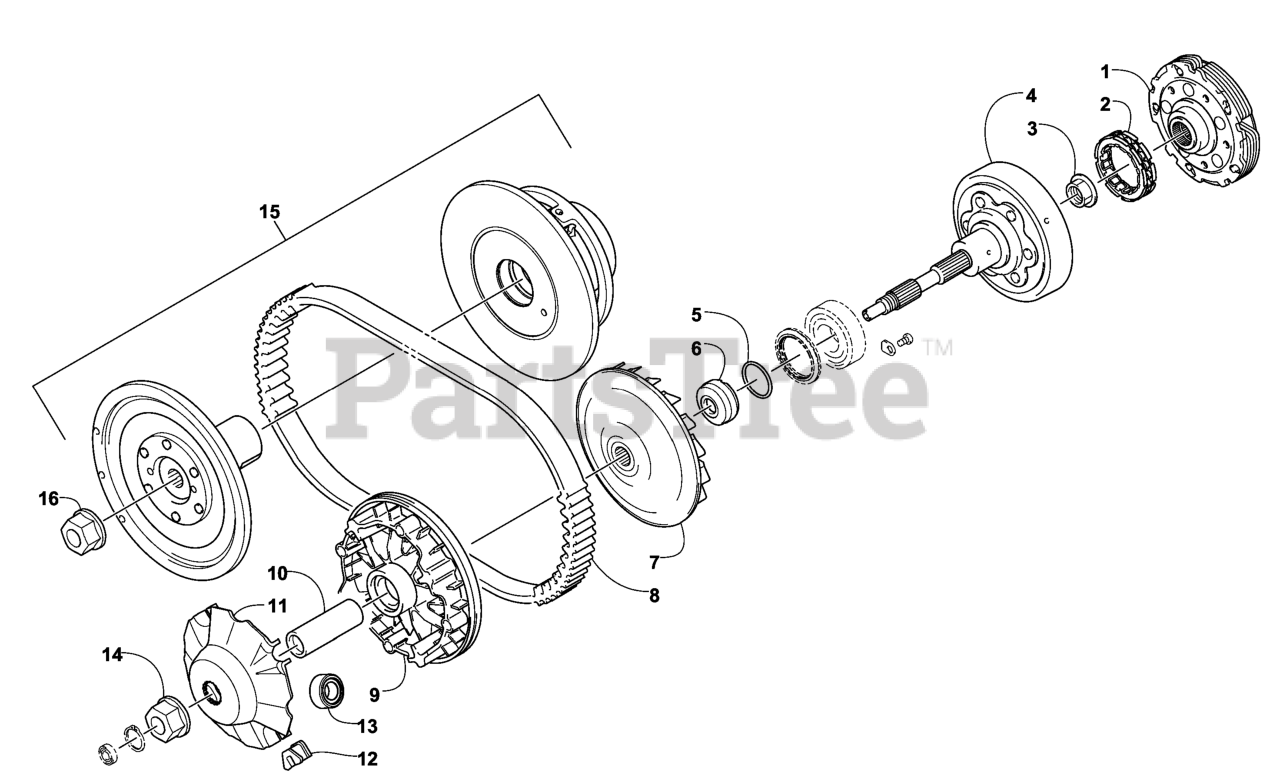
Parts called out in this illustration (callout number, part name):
1	PRIMARY CLUTCH ASM
2	CLUTCH-ONE WAY
3	NUT-HHF, CCW
4	PRIMARY DRIVE GEAR ASM
6	SPACER-FIXED DRIVE FACE
7	FACE-DRIVE
9	FACE-COMP, MOVABLE
10	SPACER-MOVABLE DRIVE FACE
12	DAMPER-MOVABLE DRIVE FACE
14	NUT-HHF
15	DRIVEN PULLEY ASM
16	NUT-HHF
